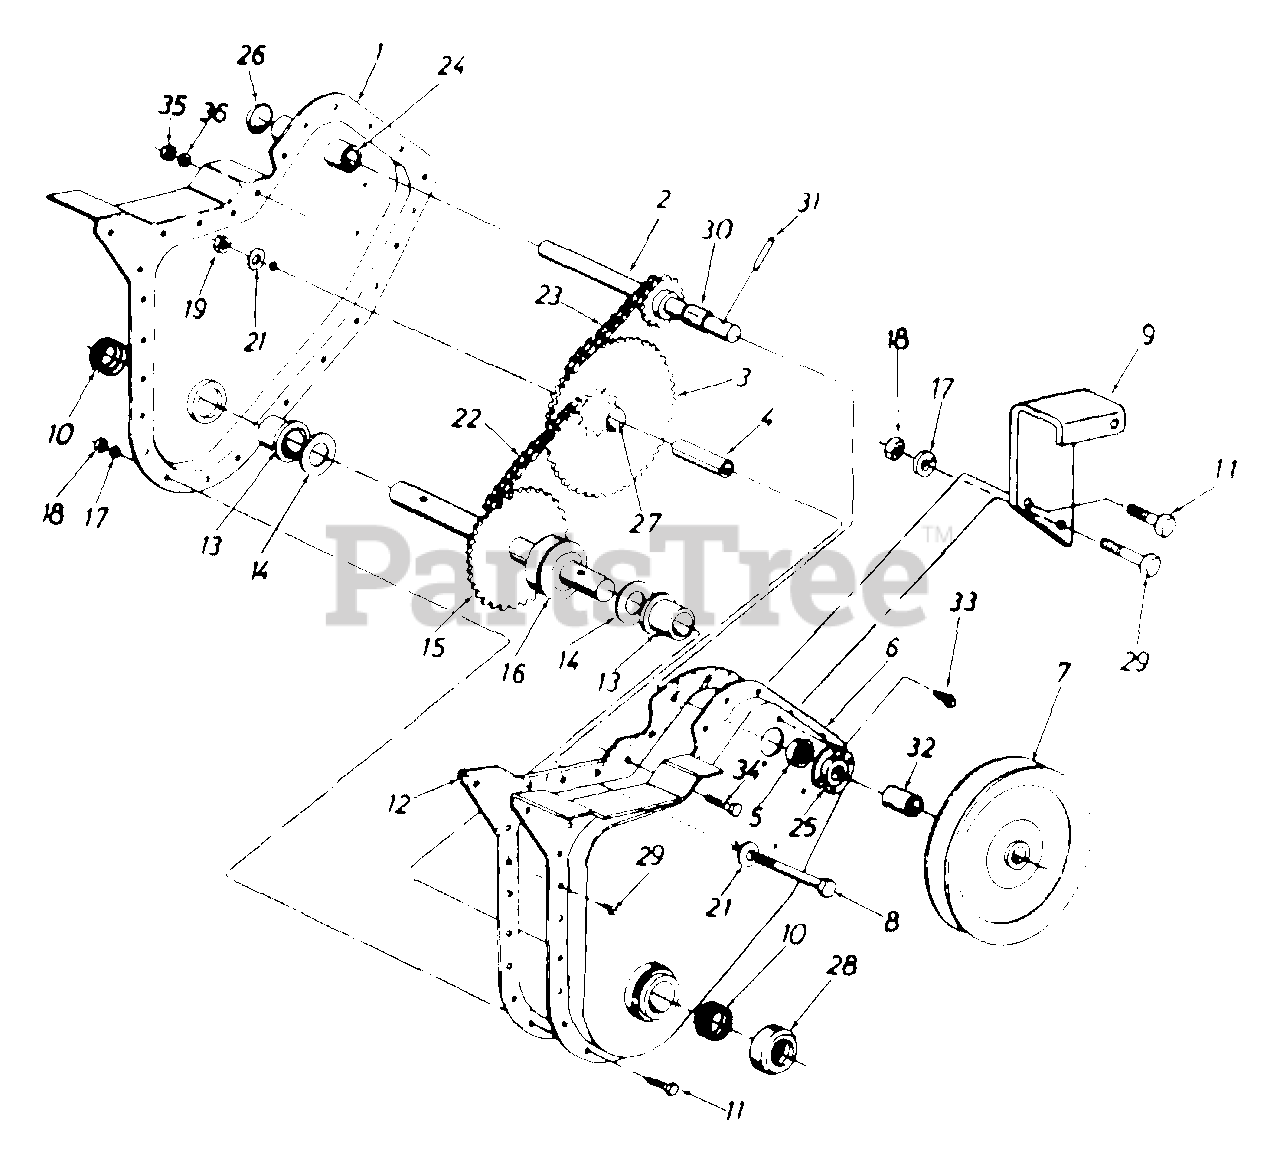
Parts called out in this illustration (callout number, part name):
1	Chain Case Ass'y. - R.H.
2	Input Shaft Ass'y.
3	Hub and Sprocket Ass'y.
4	Bearing Inner Race
5	Ball Bearing
8	Hex Bolt 3/8-24 x 2.5"
9	Belt Cover Brkt.
11	Hex Bolt 1/4-28 x .625"
12	Gasket
13	Flange Brg. .879" I.D.
14	Fl-Wash. .88" I.D. x 1.5"
15	Tine Shaft Ass'y.
16	Spacer 7/8" I.D.
17	L-Wash. 1/4" I.D.
18	Hex Nut 1/4-28 Thd.
19	Hex Ins. L-Nut 3/8-24 Thd.
21	Bell-Wash. .406" I.D.
22	Chain #420 1/2" Pitch 38 Links
23	Chain #35 .375" Pitch 50 Links
24	Bearing .62" I.D. x .813"
25	Bearing Housing
26	Expansion Plug 13/16" Dia.
27	Bearing
29	Hex Wash. Hd. Self-Tap Scr. 1/4-20 x .50" Lg.
30	Spacer .63" I.D. x .77" O.D. x .38" Lg.
31	Spring Pin Spiral 1/4" Dia. x 1-1/2" Lg.
32	Spacer .647 x 1.25"
33	Hex Wash. Hd. Self-Tap Scr. 1/4-20 x .38" Lg.
34	Hex Bolt 5/16-18 x .75"
35	Hex Nut 5/16-18 Thd.
36	L-Wash. 5/16" I.D.
